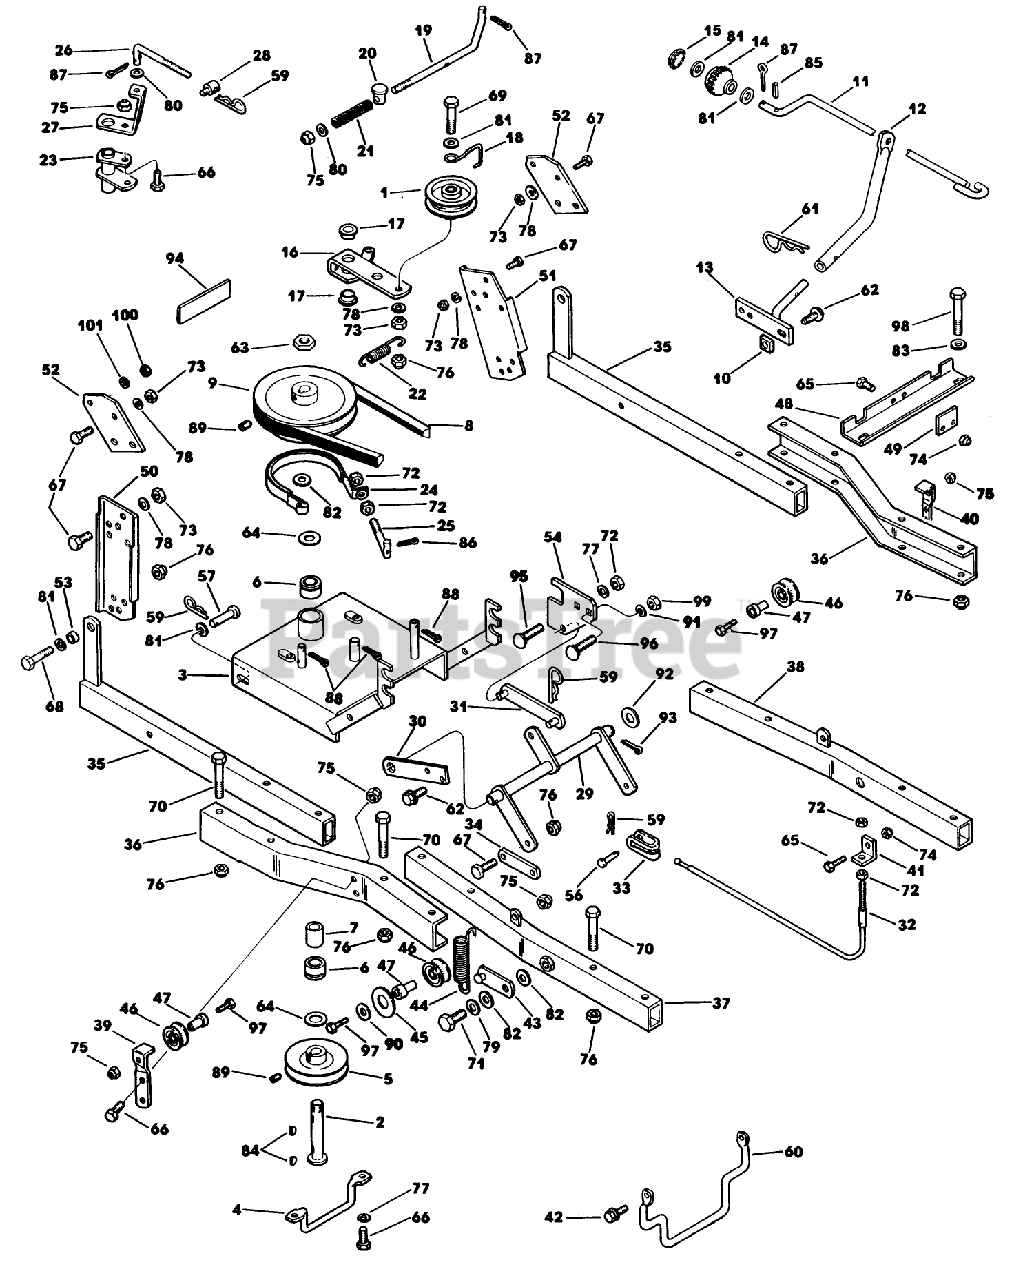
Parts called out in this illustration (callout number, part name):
9	Pulley Brake Drum Assembly
21	Spring
77	Lock Washer 5/16 Plated
96	Bolt, Carriage 7/16 14 x 1" Plated
101	Lock Washer 5/16 Plated
